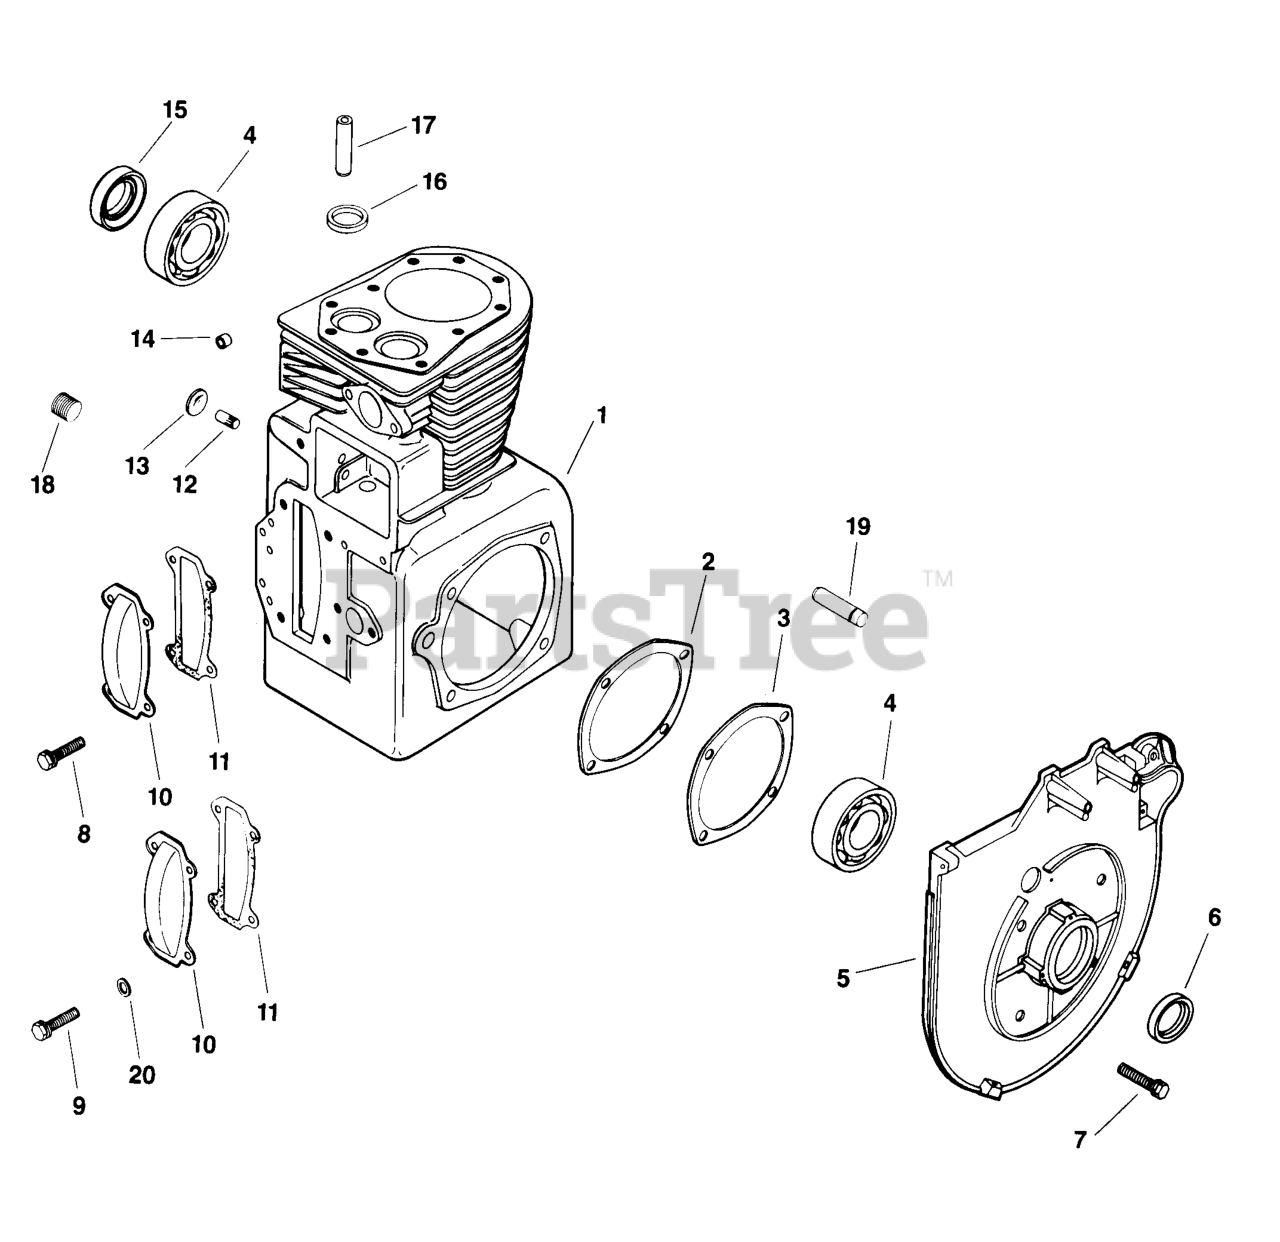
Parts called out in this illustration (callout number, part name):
1	Cylinder Block
3	GASKET, BEARING PLATE - DISCONTINUED
4	BEARING, BALL
5	PLATE, BEARING - DISCONTINUED
6	SEAL, FRONT OIL
7	SCREW, SEMS 3/8-16-X1"
9	SCREW, SEMS 1/4-20-1/2"
10	COVER, CAMSHAFT - DISCONTINUED
11	GASKET, CAMSHAFT COVER
12	SHAFT, GOVERNOR GEAR
13	PLUG, WELCH EXPANSION
14	BEARING
15	SEAL, REAR OIL
17	GUIDE, VALVE - DISCONTINUED
